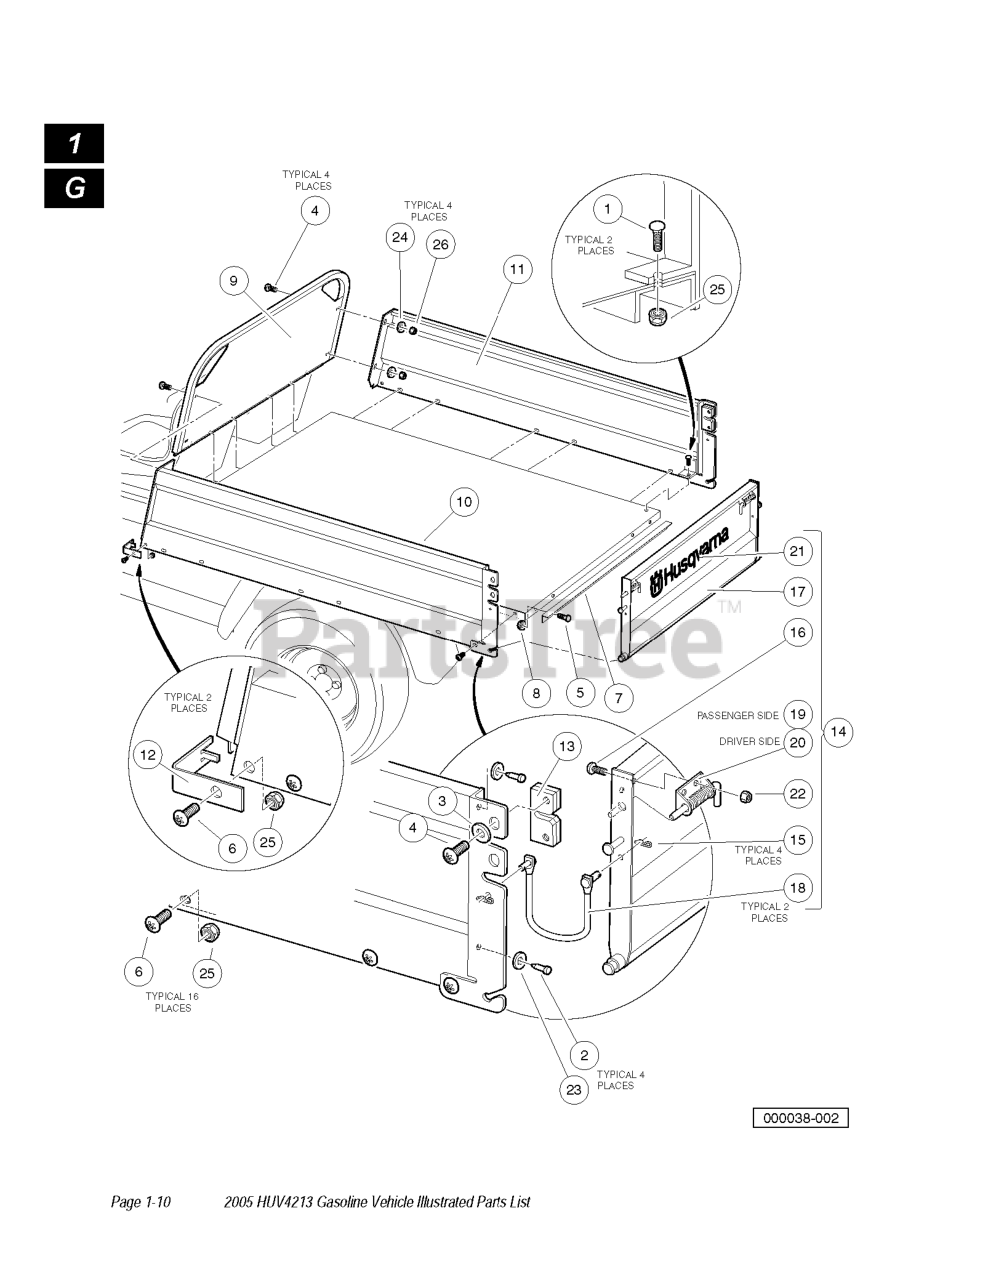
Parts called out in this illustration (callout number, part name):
1	BOLT, 5/16-18 X 1.00 SQ.NECK
2	RUBBER BUMPER
6	SCREW, 5/16-18 X .88 TRX TRUSS
7	DECAL, BED LOAD WARNING
8	BOX BED TAILGATE ANGLE
9	LOCKNUT, 5/16-18 HEX FLANGE
10	FRONT PANEL WELDMENT
11	LEFT PANEL WELDMENT
12	RIGHT PANEL WELDMENT
13	FRONT CORNER CAP
14	SLAM LATCH
15	ASM, TAILGATE, OEM
16	HAIR PIN CLIP
19	TETHER ASSEMBLY
20	SPRING LATCH RIGHT
21	SPRING LATCH LEFT
22	DECAL, TAILGATE,OEM
23	LOCKNUT, 1/4-20 NYLON INSERT
24	WASHER, RUBBER 3/8
25	WASHER 1/4 FLAT
26	LOCKNUT, 5/16-18 NYLON INSERT
27	LOCKNUT, 1/4-20 NYLON INSERT
